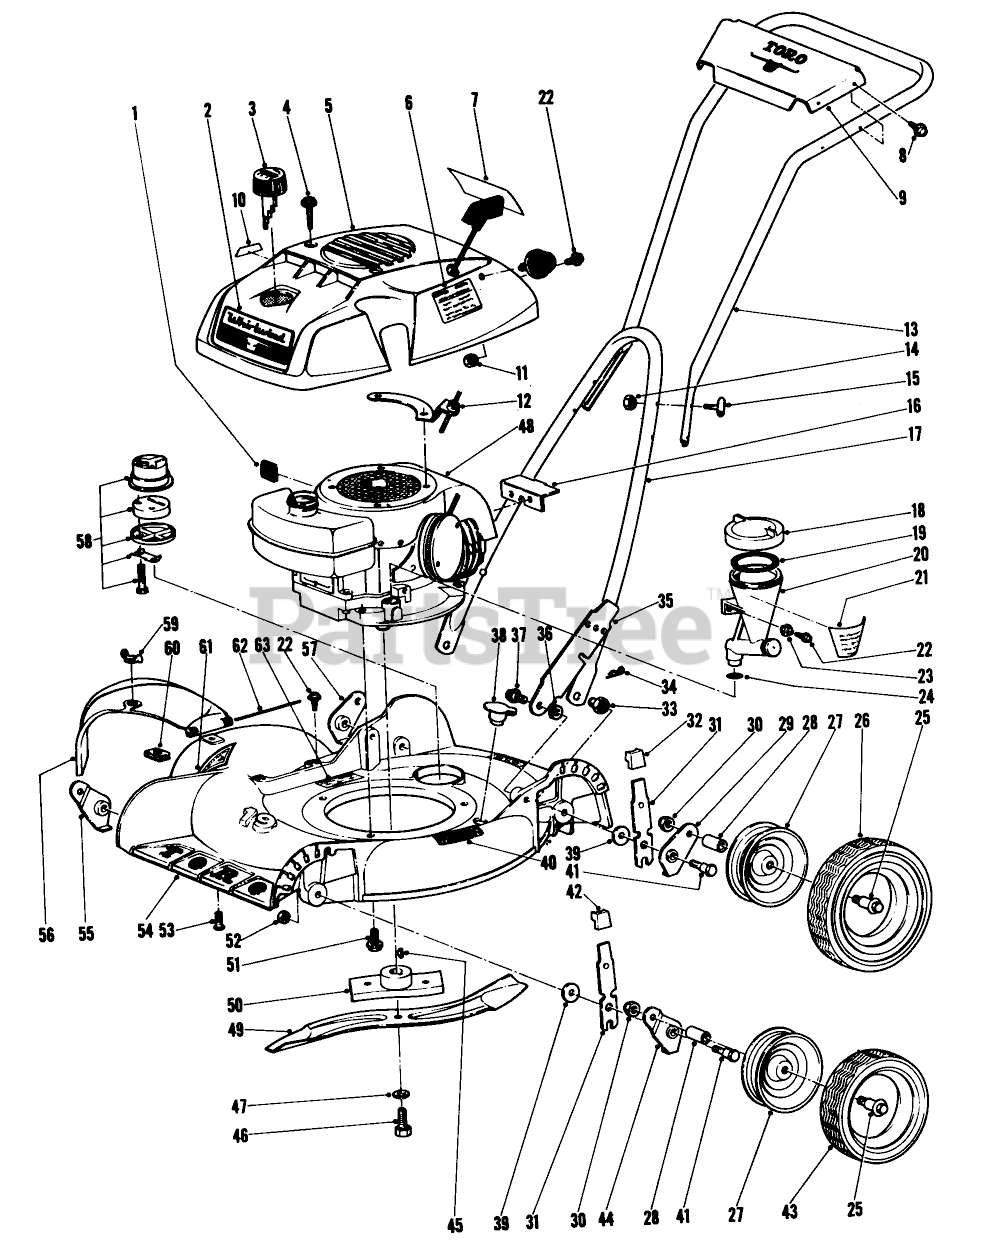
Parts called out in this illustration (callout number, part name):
1	Knob, Throttle
2	Decal
4	SCREW-HWH
5	Shroud
6	Decal-Start Prime
7	Decal
8	SCREW-HWHTF
9	Escutcheon
10	Decal
11	NUT-KEPS
12	Bracket,Recoil
13	Handle-Upper
16	Bracket
17	Handle-Lower
18	Cap, Reservoir (Incl. Ref. 15)
21	Decal, Reservoir
23	Washer
24	O-RING
29	Pivot Arm
30	NUT-HEX
31	Spring Arm
34	PIN-COTTER, HAIR
36	SPACER
37	SCREW-SHOULDER
41	5/16-18 PIVOT SCREW
42	ARM KNOB
44	Arm, Pivot
45	KEY-WOODRUFF
47	WASHER-LOCK
48	Engine Recoil
50	BLADE RETAINER WA
55	Arm, Pivot
57	Pivot Arm
59	NUT-WING SPECL
60	NUT-SPEED
61	Decal
